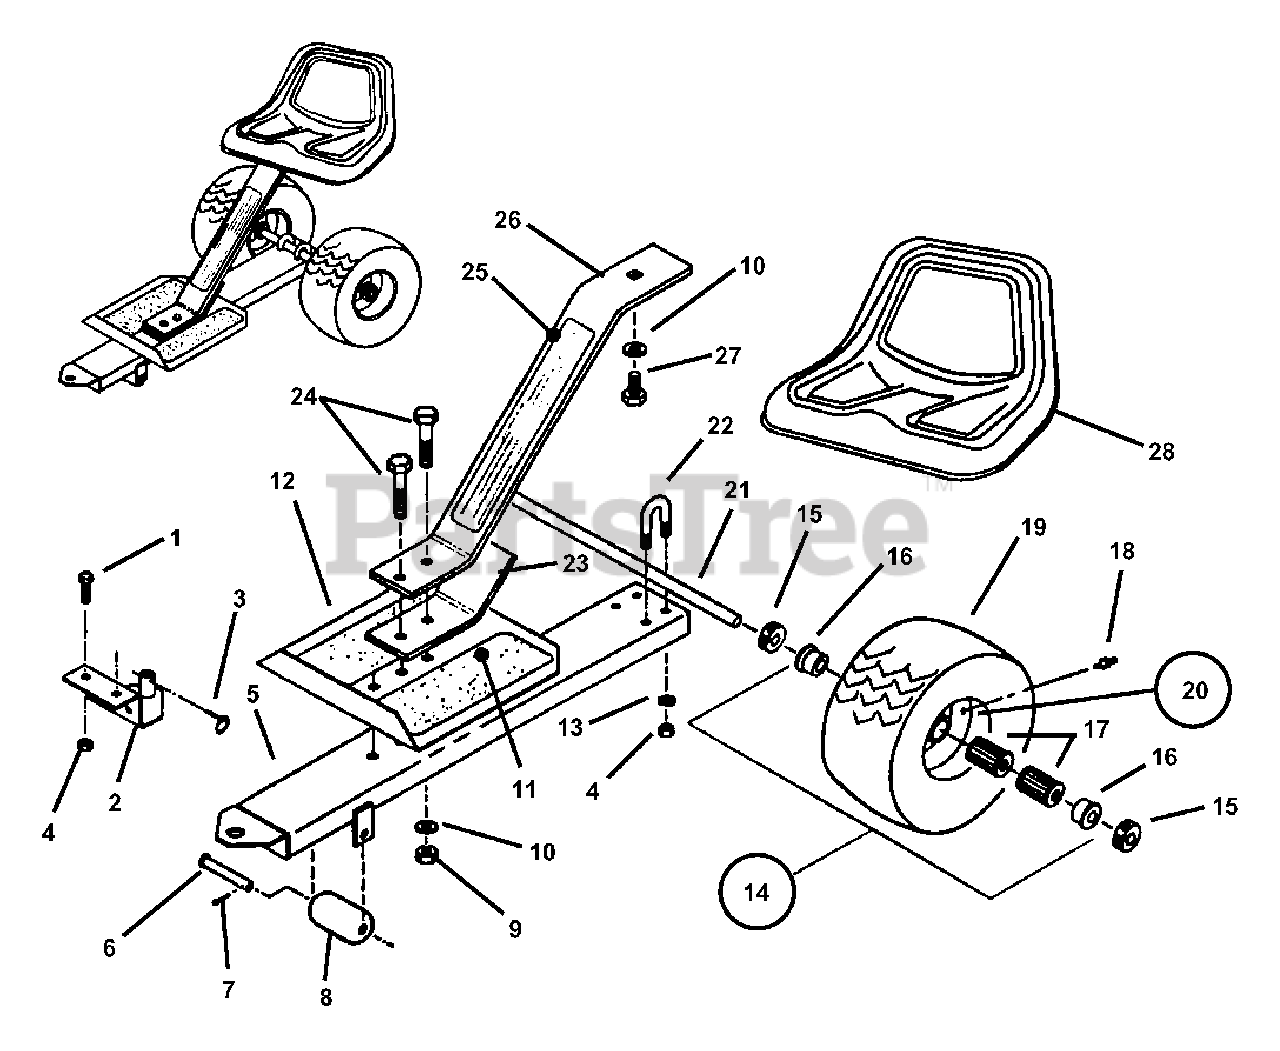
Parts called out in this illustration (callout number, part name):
1	SCREW, 5/16-18 x 1" Hex
2	WELDMENT, Hitch
3	PIN, Lynch
4	NUT, 5/16-18 Hex Nyloc
5	WELDMENT, Frame
6	AXLE, Roller
7	PIN, 1/8 x 1-1/2" Cotter
8	ROLLER
9	NUT, 1/2-13 Hex, Gr. 5 or B
10	WASHER, 1/2" Split Lock
11	PAD, Abrasive
12	FOOT REST (w/o pad)
13	WASHER, 5/16" Flat
14	ASS'Y, Tire
15	CLAMP, Collar
16	BEARING, Flange
17	BEARING, Roller
18	FITTING, 1/4-28 Grease
19	TIRE, 2 Ply Turfmaster
20	ASS'Y, Rim
21	AXLE, Main
22	U-Bolt (5/16-18 threads)
23	STIFFENER
24	SCREW, 1/2-13 x 2" Hex
25	DECAL, Warning
26	SPRING, Seat
27	SCREW, 1/2-13 x 1" Hex Head
28	SEAT w/Decal
